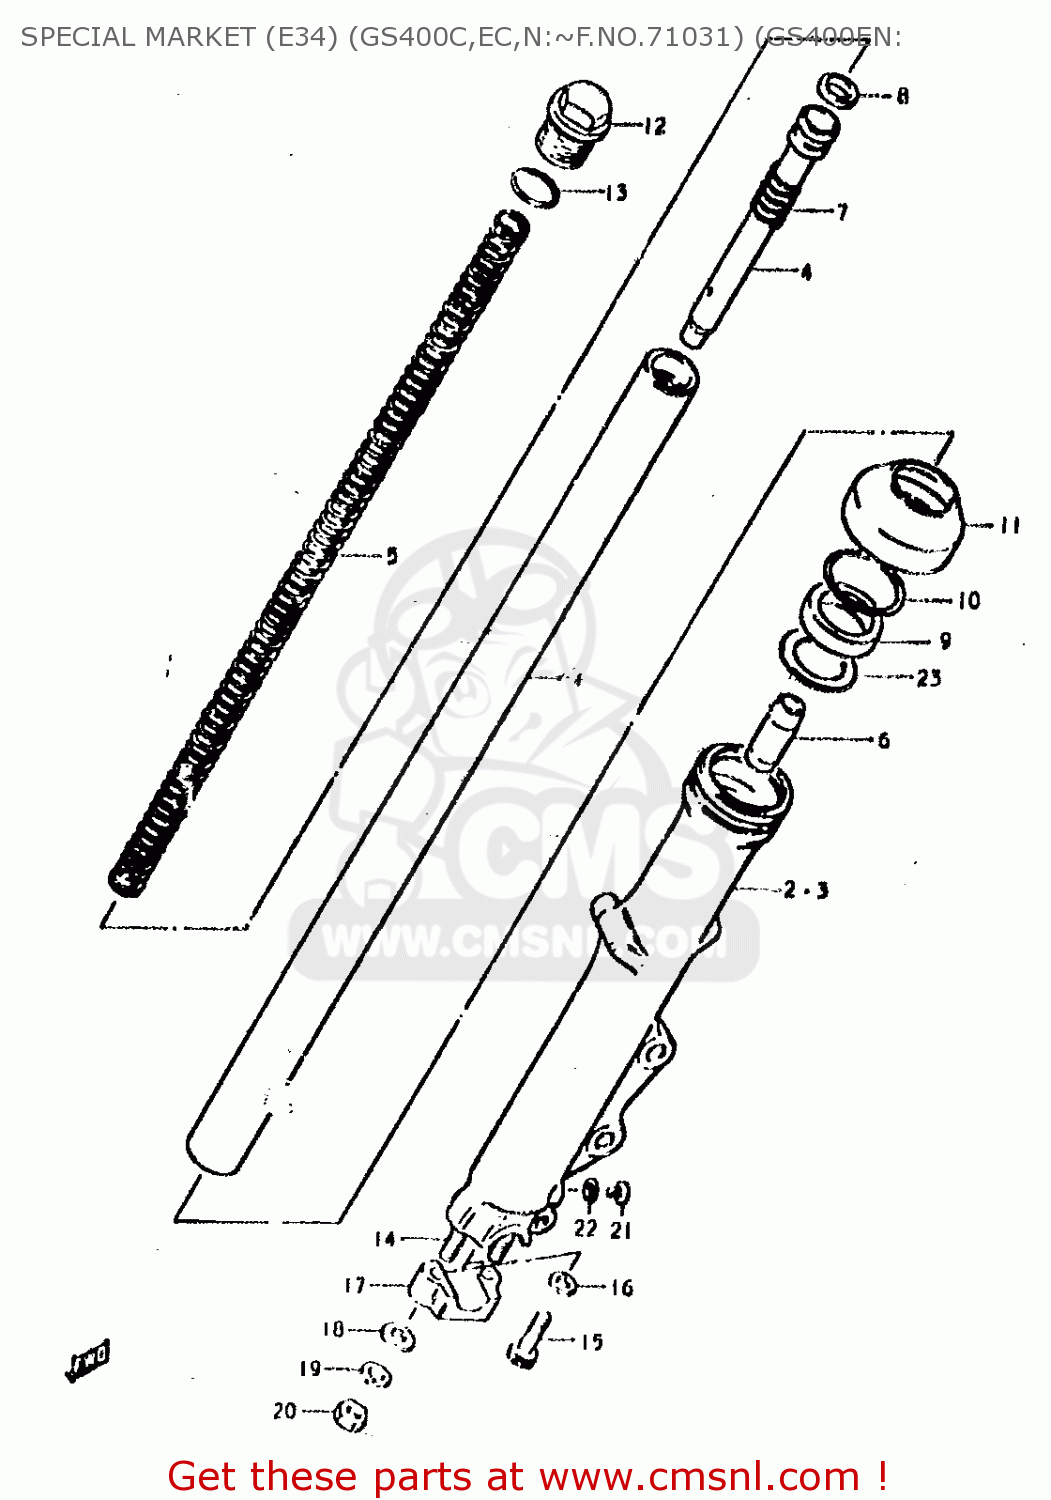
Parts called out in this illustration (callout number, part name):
1	TUBE,INNER
2	TUBE,FORK,LEFT,OUTER
3	TUBE,FORK,OUTER,RIGHT
4	CYLINDER,FRONT FORK
5	SPRING
6	PIECE,OIL LOCK
7	SPRING,REBOUND
8	RING,PISTON
9	OIL SEAL,FRONT FORK
10	CIRCLIP,FORK OIL SEAL
11	BOOT
12	BOLT
13	O RING
14	STUD 8X25
15	BOLT
16	GASKET (NAS)
17	HOLDER,AXLE
18	WASHER
19	LOCK WASHER
20	NUT
21	SCREW
22	GASKET (NAS)
23	SPACER,OIL SEAL
